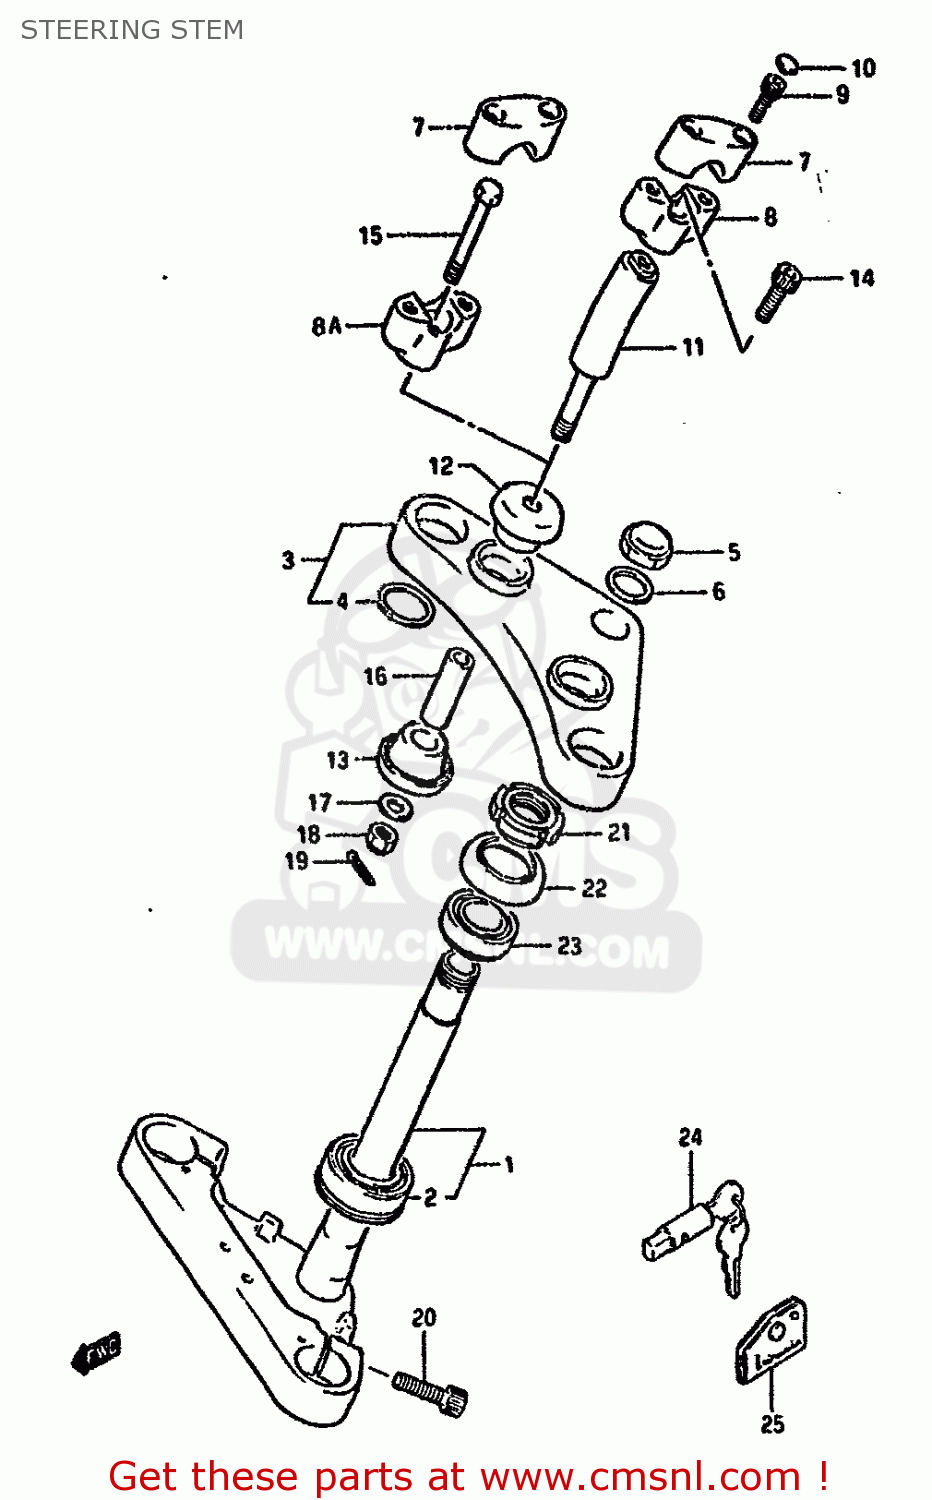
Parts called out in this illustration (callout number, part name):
1	STEM,STEERING
2	BEARING(30X55X17)
3	HEAD,STEERING STEM
4	WASHER,STEM HEAD,LOWER
5	NUT,CAP
6	WASHER(22.5X32X1.6)
7	HOLDER,HANDLE UPR
8	HOLDER,HANDLE LWR
8A	HOLDER,HANDLE LWR
9	BOLT, LH
10	CAP(OD:14.5)
11	ARM
12	CUSHION,UPR
13	CUSHION,LWR
14	BOLT
15	BOLT,HANDLBAR CLAMP
16	SPACER(10.2X14X46)
17	WASHER 10MM
18	NUT
19	PIN 20X20
20	BOLT, (10X30)
21	NUT,STEERING STEM(25X44X10)
22	SEAL,STEERING UPR DUST
23	TAPER,ROLLER BEARING
24	LOCK ASSEMBLY,STEERING (NEI
25	CASE,STEERING KEY
